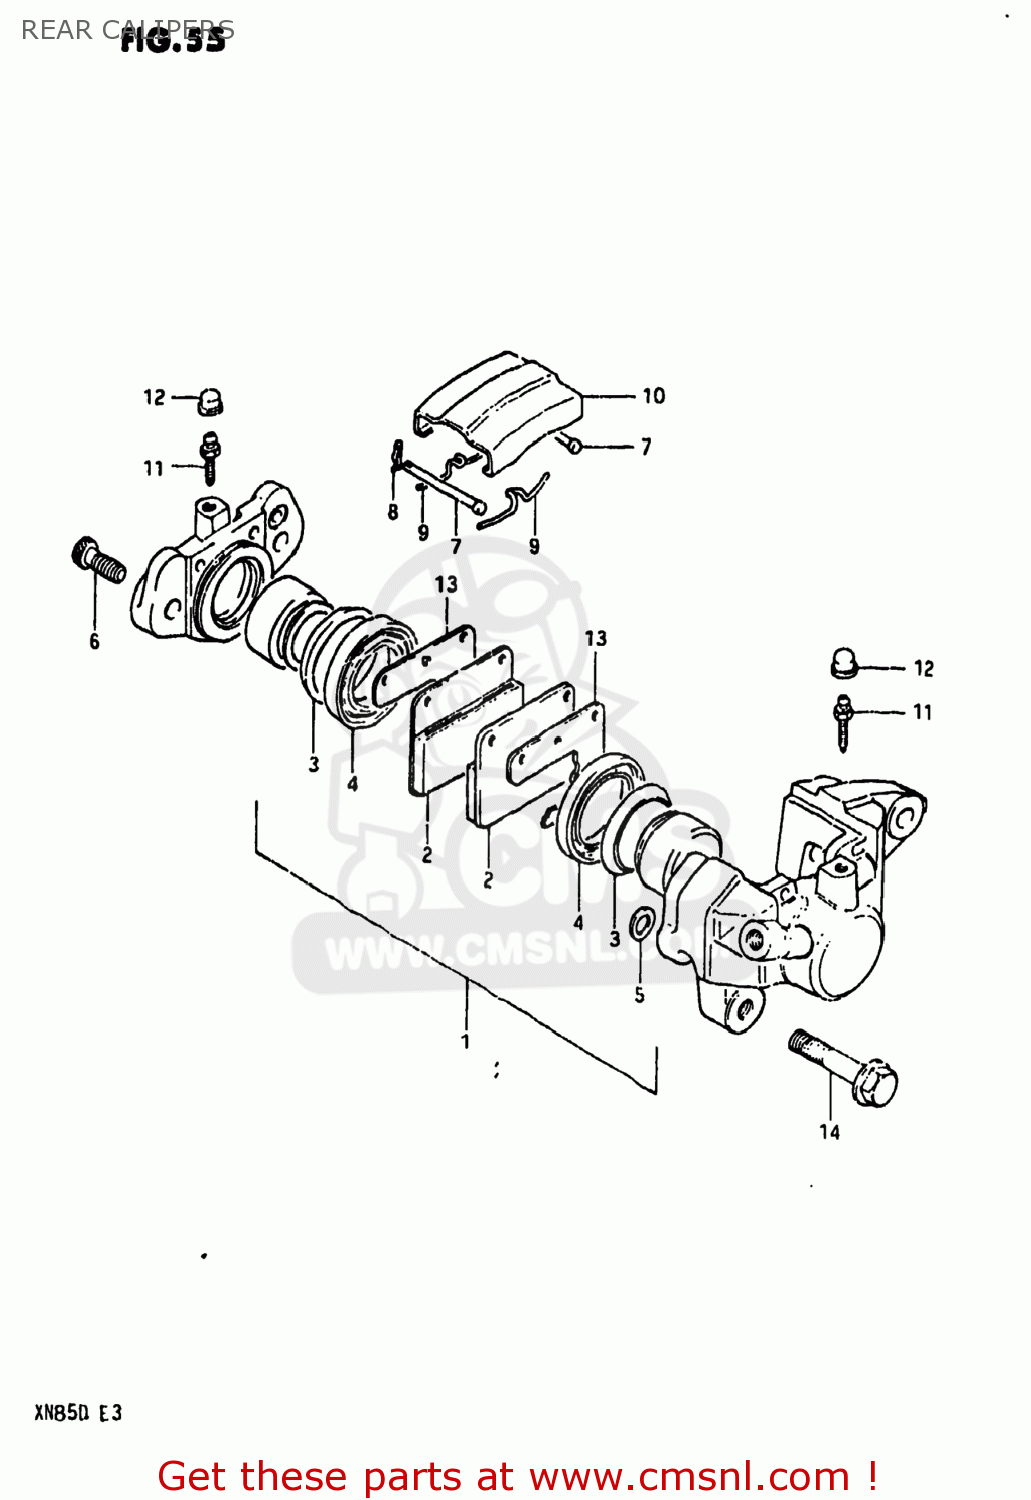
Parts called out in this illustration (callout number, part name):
1	PISTON SET
2	PAD,BRAKE (MCA)
3	SEAL,PISTON
4	BOOT,PISTON
5	SEAL,PISTON
6	BOLT,HOUSING
7	PIN,PAD
8	CLIP,PAD PIN
9	SPRING
10	COVER,DUST
11	BLEEDER
12	CAP,BREATHER
13	SHIM,RR CALIPER
14	BOLT
